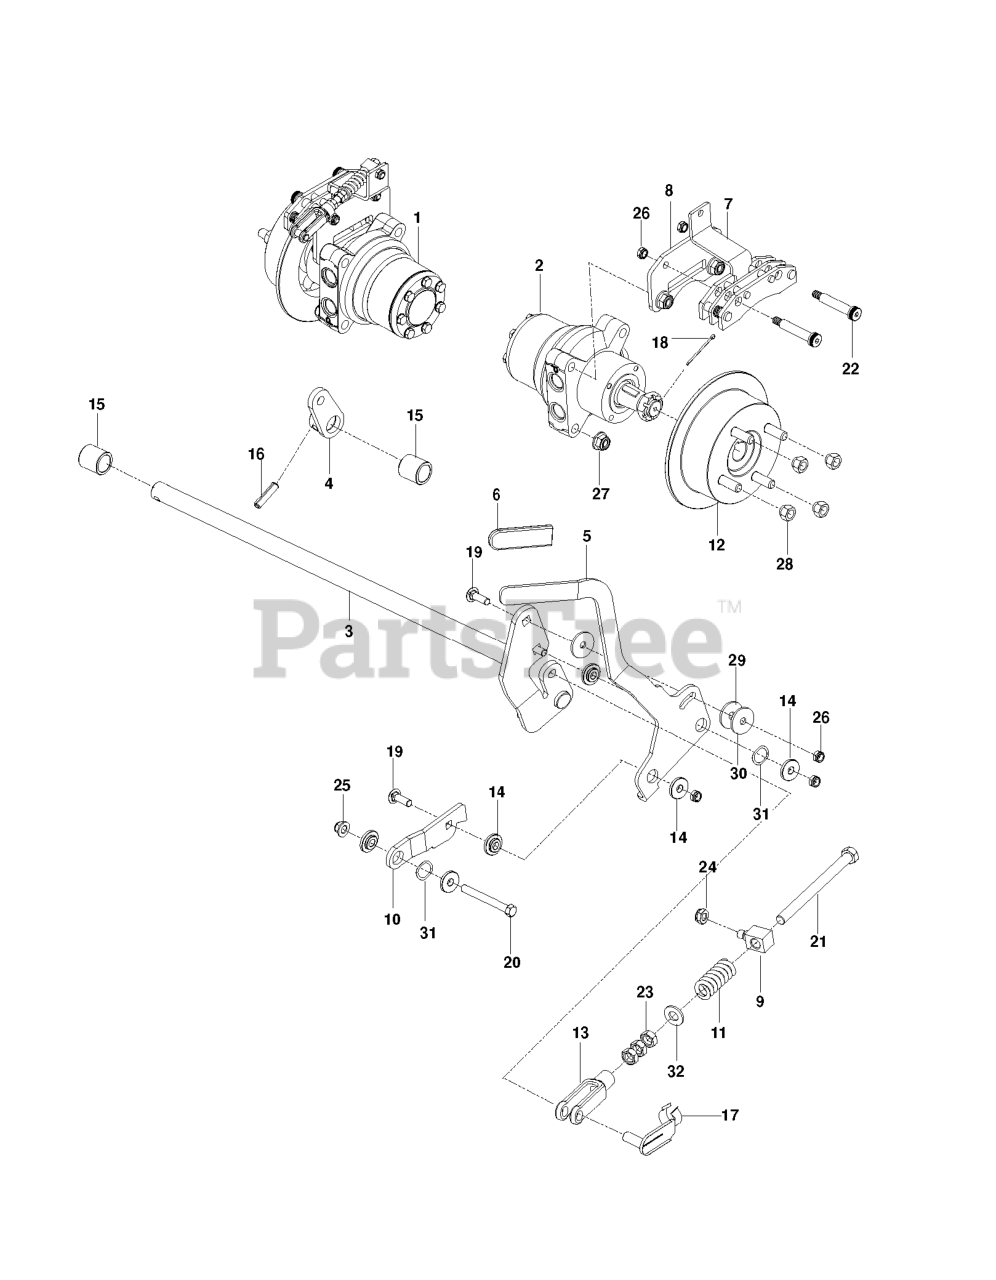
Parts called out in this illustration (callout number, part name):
1	MOTOR, TL0310, RT
2	MOTOR, TL0310, LT
3	SHAFT, BRAKE WLDMT
4	ARM, RT BRAKE
5	LEVER.BRAKE.BLACK
8	PLATE, CALIPER
9	SWIVEL, BRAKE
10	LINK, FOLLOWER
12	HUB, DISC BRAKE, W/STUDS
13	YOKE-3/8-24 PLTD
14	BUSHING, BRAKE
15	BUSHING, SLEEVE 3/4 X 1.0
16	5/16 DIA ROLL PIN
17	PIN, CLEVIS SPRING, 3/8
18	COTTER PIN 1/8 X 2
19	RHSNB 3/8-16 X 1-1/4
20	HCS 3/8-16 X 3-1/4 GR5 ZD
21	HCS 3/8F X SPECIAL
22	BOLT, SHOULDER, 1/2 X 2.25
23	NUT 3/8-24 JAM
24	5/16-18 THIN PROF NY
25	NUT 3/8-16 HEX FLG NYLOC ZD
26	NUT HEX 3/8-16 NYLON, THIN
27	NUT, 1/2-13 HEX FLG NYLOC ZD
28	LUG NUT 1/2F
29	WASHER, FRICTION, 1/8
30	CONE WASHER
31	WASHER, .825 X 1.087, WAVE
32	WASHER 3/8 SAE FLAT
